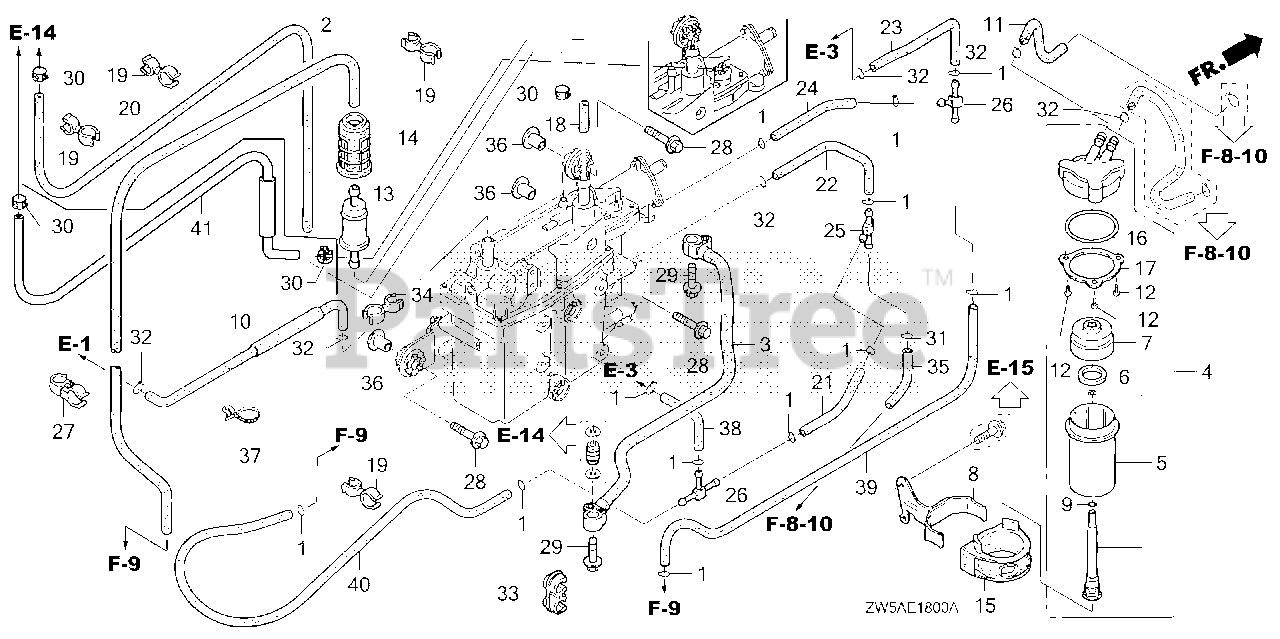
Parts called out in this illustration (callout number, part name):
1	CLIP, TUBE
2	TUBE B, AIR VENT
3	HOSE, FUEL
4	SEPARATOR ASSY., WATER
5	CUP, WATER SEPARATOR
7	BUFFER, PLATE
8	STAY, WATER SEPARATOR
10	TUBE, FUEL (D)
11	TUBE E, FUEL
12	SCREW, PAN (5X12)
13	FILTER, FUEL PUMP
14	SUSPENSION, STRAINER
15	SUSPENSION, STRAINER
18	TUBE B, FUEL
19	CLAMP, HOSE
20	HOSE, PRESSURE REGULATOR RETURN
21	TUBE A, WATER
22	TUBE B, WATER
23	TUBE C, WATER
24	TUBE D, WATER
25	T-JOINT
26	JOINT, THREE WAY
27	CLIP, SENSOR HOSE
28	BOLT-WASHER (8X35)
29	BOLT, FLANGE (6X25)
30	CLAMP, TUBE (D10.7)
31	CLIP, TUBE (B10)
32	CLIP, TUBE (B12)
33	CLAMP, FUEL TUBE
34	CLAMP (6MM-12MM)
35	TUBE, WATER CHECK
36	COLLAR (8.5X14.5)
37	CLIP, TUBE (135MM) (BLACK)
38	BULK HOSE, VACUUM (7X3000) (7X100)
39	BULK HOSE, VACUUM (7X3000) (7X550)
40	BULK HOSE, VACUUM (7X3000) (7X690)
41	HOSE, PRESSURE REGULATOR RETURN
